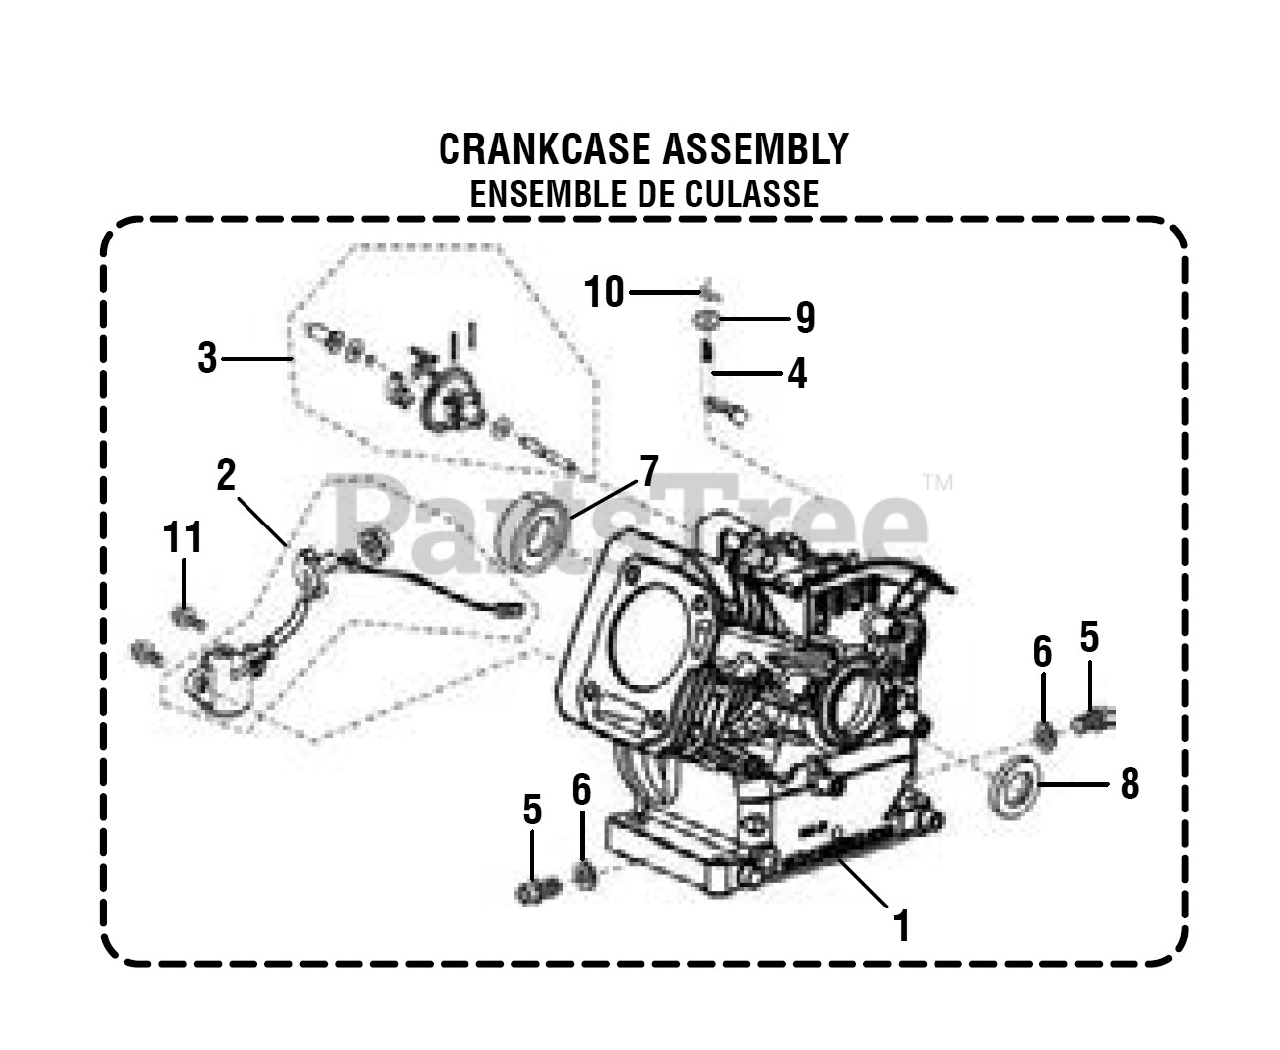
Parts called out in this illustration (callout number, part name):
1	Crankcase Assembly
2	Engine Oil Sensor
3	Governor Gear Assembly
4	Governor Arm
5	Drain Plug
6	Washer
7	Ball Bearing
8	Oil Seal
9	Washer
10	Pin
